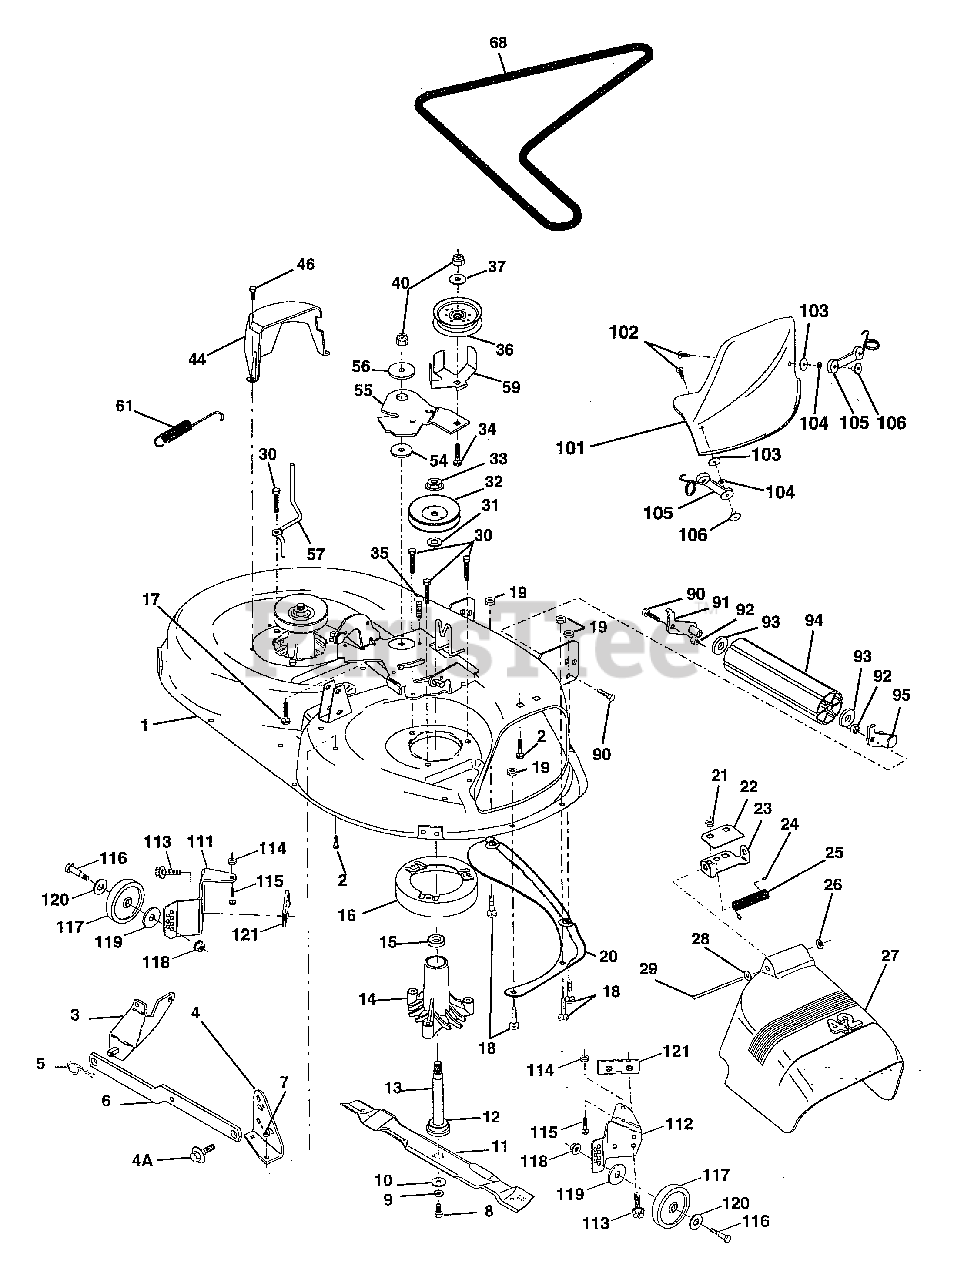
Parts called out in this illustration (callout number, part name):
1	Deck Asm MWR 42" weldment
2	Bolt Rdhd Sqnk 5/16-18unc X3/4
3	Bracket Asm Fr Sway Bar 38/42
4	Bracket Asm Deck 42" sway Bar
4A	Bolt Shoulder
5	Retainer Spring
6	Arm Suspension Rear
7	Locknut-hex W/ins 5/16-18unc P
8	Bolt 3/8-24x1 25 Gr8 Patched
9	Washer Lock Hvy 3/8 Unplated
10	Washer Hard Blade Mower Vented
11	Blade Mower Mulching 42"
12	Bearing Ball #6204 (Mandrel)
13	Shaft Asm W/lower Bearing
14	Housing Mandrel Vented (machd)
15	Bearing Ball Mandrel
16	Stripper Mower Vented
17	Bolt Rdhd Sqnk 3/8-16 X 1-1/4
18	Bolt Carr 5/16-18 X 5/8
19	Locknut-hex W/ins 5/16-18unc P
20	Baffle Vortex 42
21	Nut Lock 5/16-18
22	Stiffener Bracket 42" deck
23	Bracket Deflector Mower 42"
24	Cap Sleeve 80x 112 Blk Mower
25	Spring Torsion Deflector 252
26	Nut Push Phos & Oil
27	Shield Deflector Mower 42" BIk
28	Washer 11/32 X 5/8 X 16 Ga
29	Rod Hinge 42"6 75 Wlg
30	Screw Thdrol Hex Hd Zinc Mwr.
31	Washer Spacer Mower Vented
32	Pulley Mandrel 42"
33	Nut 9/16top Lock Fing Cntr
34	Bolt Rdhd 3/8-16uncx2-3/4 Gr5
35	Fastner Christmas Tree
36	Pulley Idler Flat 3 060
37	Washer 13/32 X 13/16 X 16 Ga
40	Nut Lock 3/8-16 Unc
44	Guard Mandrel LH Black
46	Screw Thdrol 1/4-20x5/8
54	Washer Hardened
55	Arm Idler 42" mower LT/YT
56	Spacer Retainer Pm Mower
57	Guide, Belt
59	Guard, Belt
61	Spring Ext. Elect
68	V-Belt Mower 42" 92 40
90	Bolt Fin Hex 3/8-16unc X 1
91	Bracket Asm Noseroller LH
92	Nut Crownlock 3/8-16 Unc
93	Washer 17/32 X 7/8 X 16 Ga
94	Roller Nose 38 & 42
95	Bracket Asm Noseroller RH.
101	Cover Mulching 42" BIk
102	Screw
103	Washer Lock #10
104	Washer #10
105	Latch Asm Bagger
106	Nut Weld .327/.304 #10-24
111	Bracket Wheel Guage Lh 42" Deck
112	Bracket Guage Wheel Rh 42" Deck
113	Bolt Hex Hd 5/16 - 18 UNC x 3/4
114	Nut Keps 5/16 - 18 UNC
115	Bolt Carriage 5/16 - Unc x 1/2
116	Bolt Shld "A" 2.41 "B" 1.66
117	Wheel Guage blk. 4.93
118	Nut Centerlock 3/8 - 16 UNC
119	Washer 3/8 x 7/8 x 14 Ga.
120	Washer 17/32 x 15/16 x 12 Ga.
